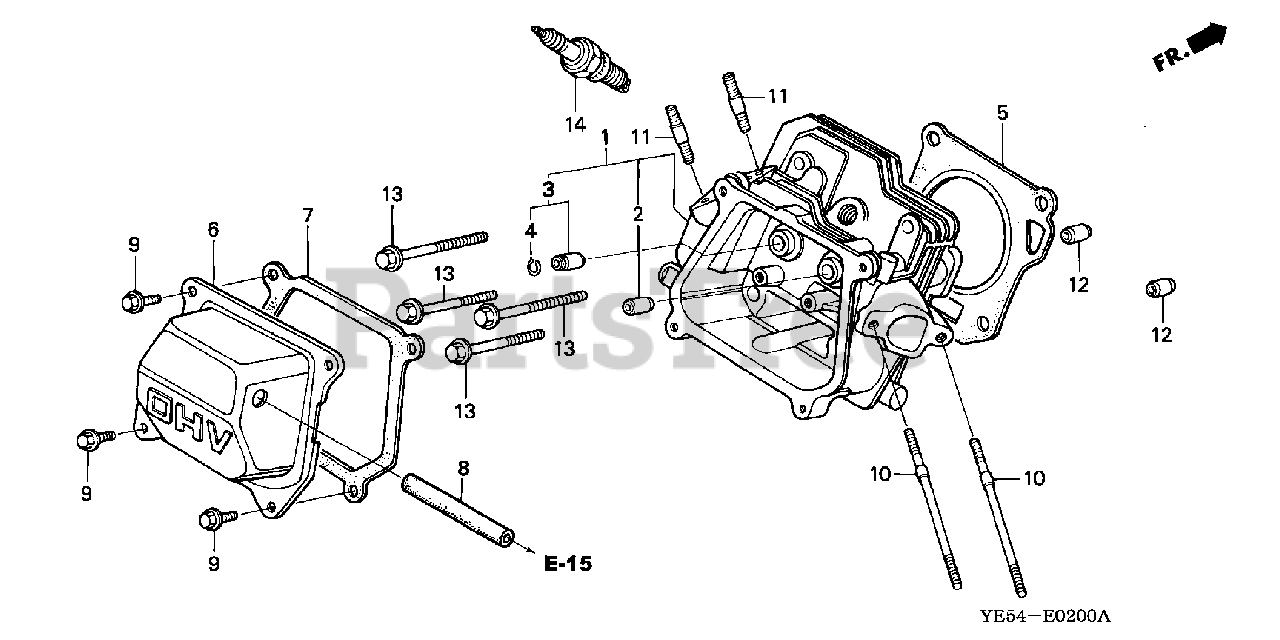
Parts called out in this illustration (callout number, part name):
1	CYLINDER HEAD
2	GUIDE, VALVE (OS)
3	GUIDE, EX. VALVE (OS)
4	CLIP, VALVE GUIDE
5	GASKET, CYLINDER HEAD
6	COVER, HEAD
7	GASKET, CYLINDER HEAD COVER
8	TUBE, BREATHER
9	BOLT, FLANGE (6X12) (CT200)
10	BOLT, STUD (6X109)
11	BOLT, STUD (8X32)
12	PIN A, DOWEL (10X16)
13	BOLT, FLANGE (8X55)
14	SPARK PLUG (BPR6ES) (NGK)
14	SPARK PLUG (W20EPR-U) (DENSO)
